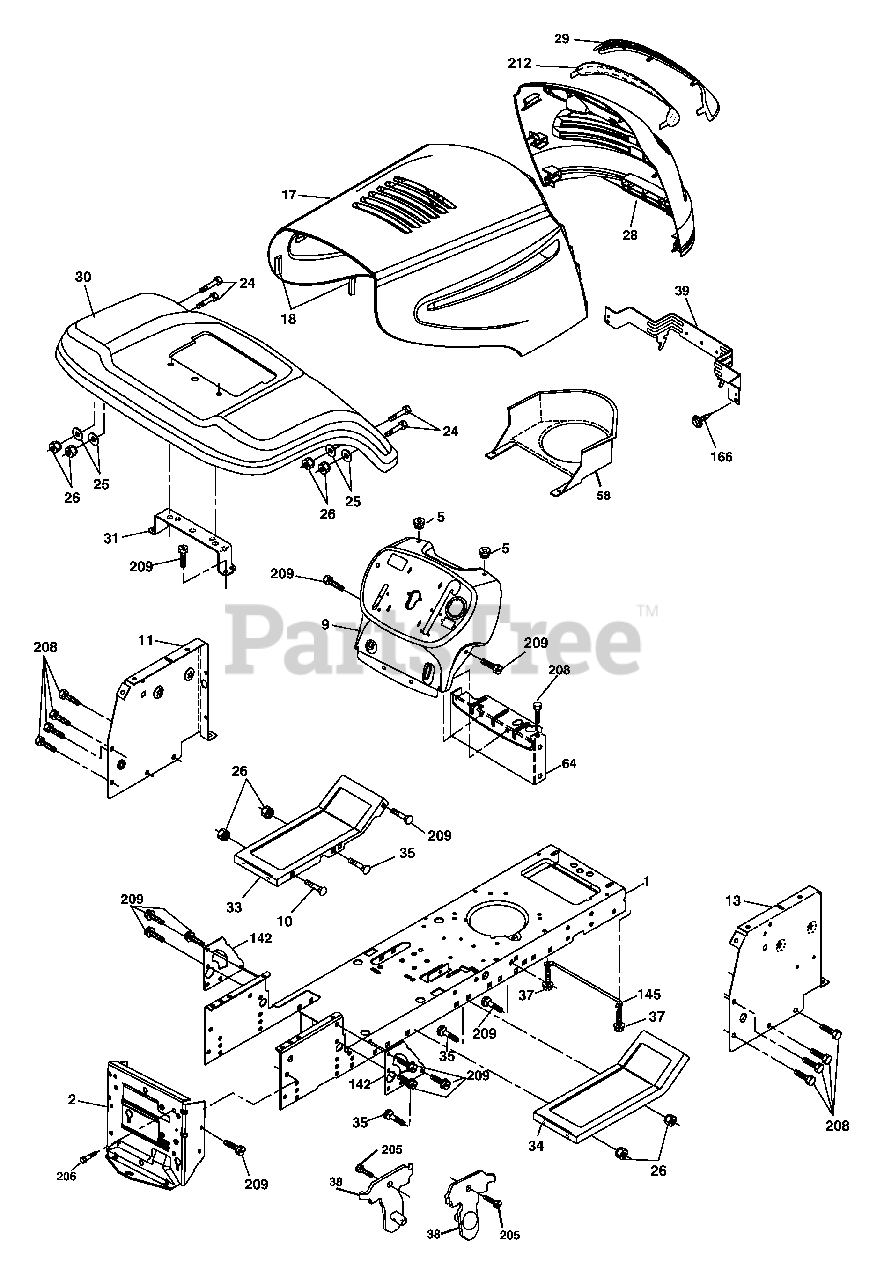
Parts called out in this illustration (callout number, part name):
1	Chassis
2	Drawbar
5	Bumper Hood/Dash
9	Dash
10	Bolt Carriage 3/8-16 x 1
11	Panel Dash Lh
17	Hood
18	Bumper Hood
24	Bolt Fin Hex 3/8-16 x 1 Gr. 5
25	Washer 13/32 x 13/16 x 12 Ga.
26	Nut Lock Hex W/Ins 3/8-16 unc
28	Grille
29	Lens
30	Fender Footrest STLT Pnt
31	Bracket Support Fender
33	Footrest Pnt Lh
34	Footrest Pnt Rh
35	Bolt Rdhd Sht Sqnk 3/8-16 x 3/4
37	Screw Thdrol 6/16-18 x 1/2 TYT
38	Bracket Asm. Pivot Mower Rear
39	Bracket Pivot
58	Duct Air
64	Dash Lower STLT
142	Plate Reinforcement STLT
145	Rod Pivot Chassis/Hood
166	Screw HWHD Hi-Lo #13-16 x 5/8
205	Screw Thdrol 3/8-16 x 1-1/4
206	Bolt Shoulder 5/16-18
207	Screw Thdrol 5/16-18x 1/2
208	Screw Thdrol 3/8-16 x 1/2
209	Screw Hex Wsh Thdr. 3/8-16 x 3/4
212	Insert Lens Reflect
278	Screw 10 x 3/4 Single Lead-Hex
